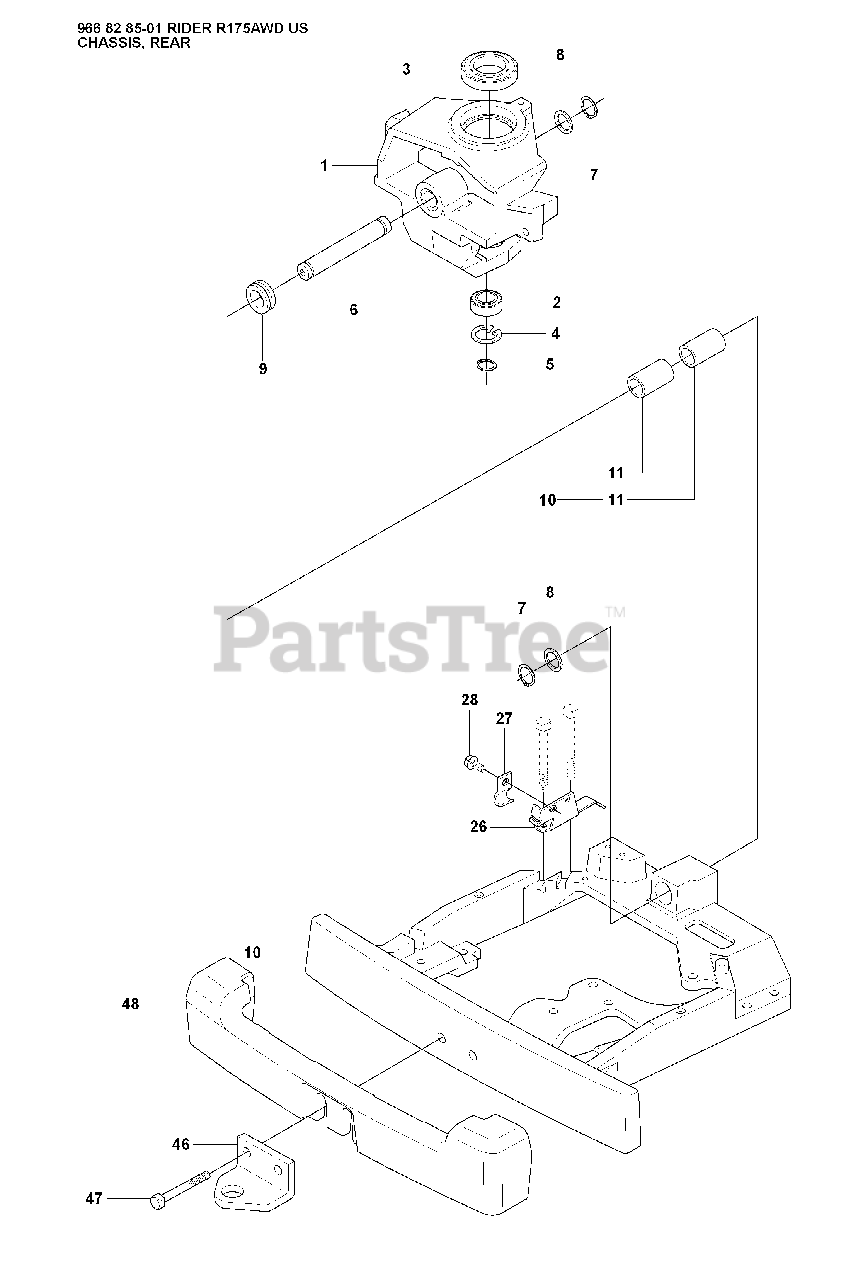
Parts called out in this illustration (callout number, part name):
2	Ball Bearing
3	BALL BEARING 6010 2RS1
4	CIRCLIP SGH 47
5	RETAINING RING SGA 25
7	RETAINING RING SGA 25
46	REPL BY 725 25 00-71
47	COUNTERWEIGHT
